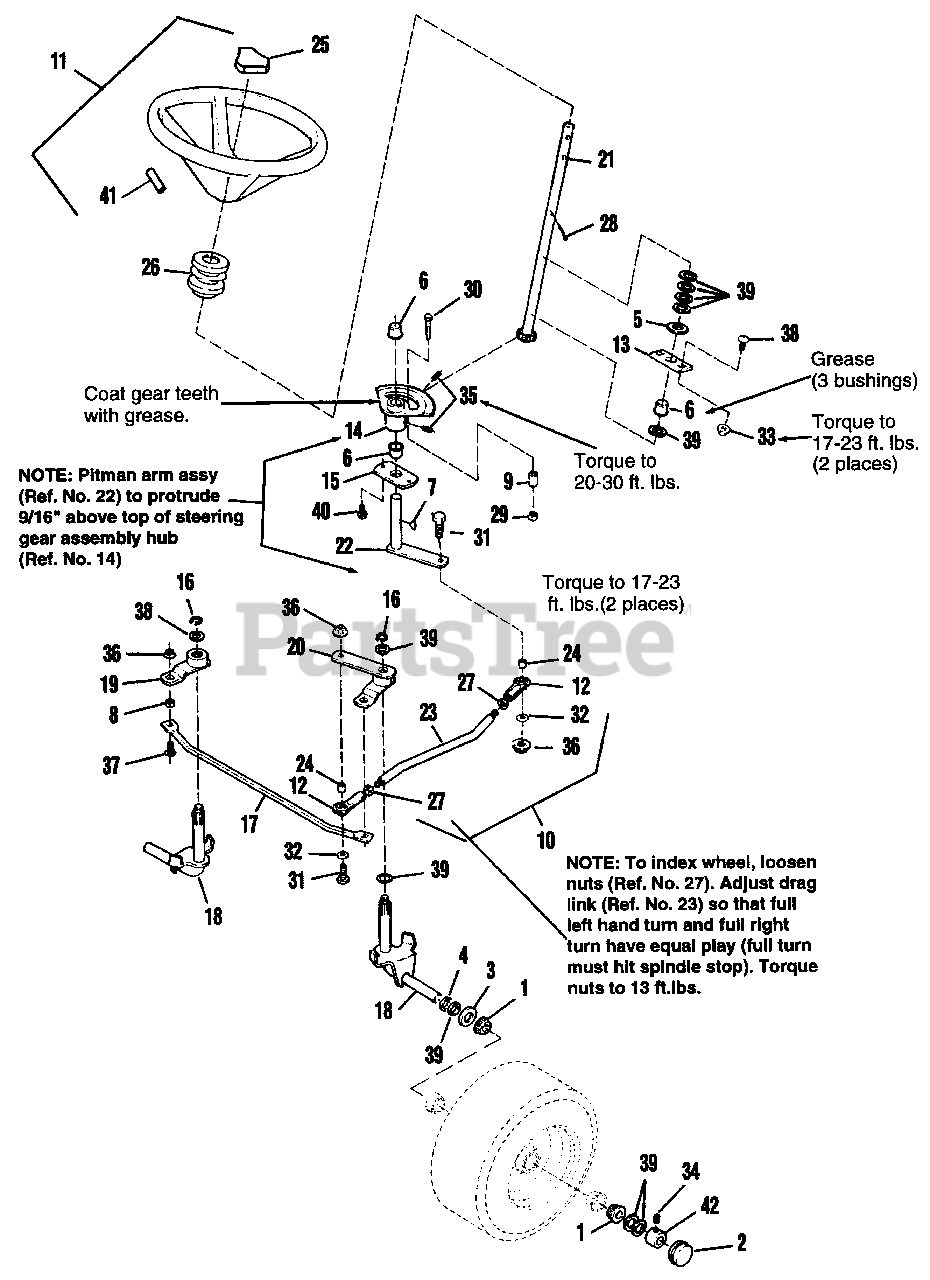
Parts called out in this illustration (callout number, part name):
1	BEARING, Cone
2	CAP, Hub
5	WASHER, Plain
6	BUSHING, Nylon
7	KEY, Hi Pro
9	SPACER, Stop
10	DRAG LINK ASSY. (Incl. Ref. Nos. 12, 23, 24, 27 & 32)
11	STEERING WHEEL, 15" (Incl. Ref. No. 25 & 41)
13	PLATE, Mounting, Steering
14	GEAR ASSY., Steering
15	SECTOR MOUNTING PLATE
18	SPINDLE ASSY.
19	ARM ASSY., Steering, RH
20	ARM ASSY., Steering, LH
21	SHAFT ASSY., Steering
22	PITMAN ARM ASSY.
25	CAP, Steering Wheel
26	TUBE, Steering
27	NUT, Hex, Jam, 1/2-20
29	NUT, Hex, Lock ESNA Light, 5/16-18
30	CAPSCREW, Hex Hd., 5/16-18 x 1-1/2
31	CAPSCREW, Hex Hd., 3/8-16 x 1-1/2
32	WASHER
33	NUT
34	SETSCREW, Sq. Hd.
35	SETSCREW, Sq. Hd., 5/16-18 x 1/2
36	NUT, Hex, Lock, Flange, 3/8-16
37	CARRIAGE BOLT, 3/8-16 x 1
39	WASHER, Plain, 49/64
40	SCREW, Taptite, 5/16-18 x 3/4
41	PIN, Spring, 5/16 x 2-1/2
42	COLLAR, Set
